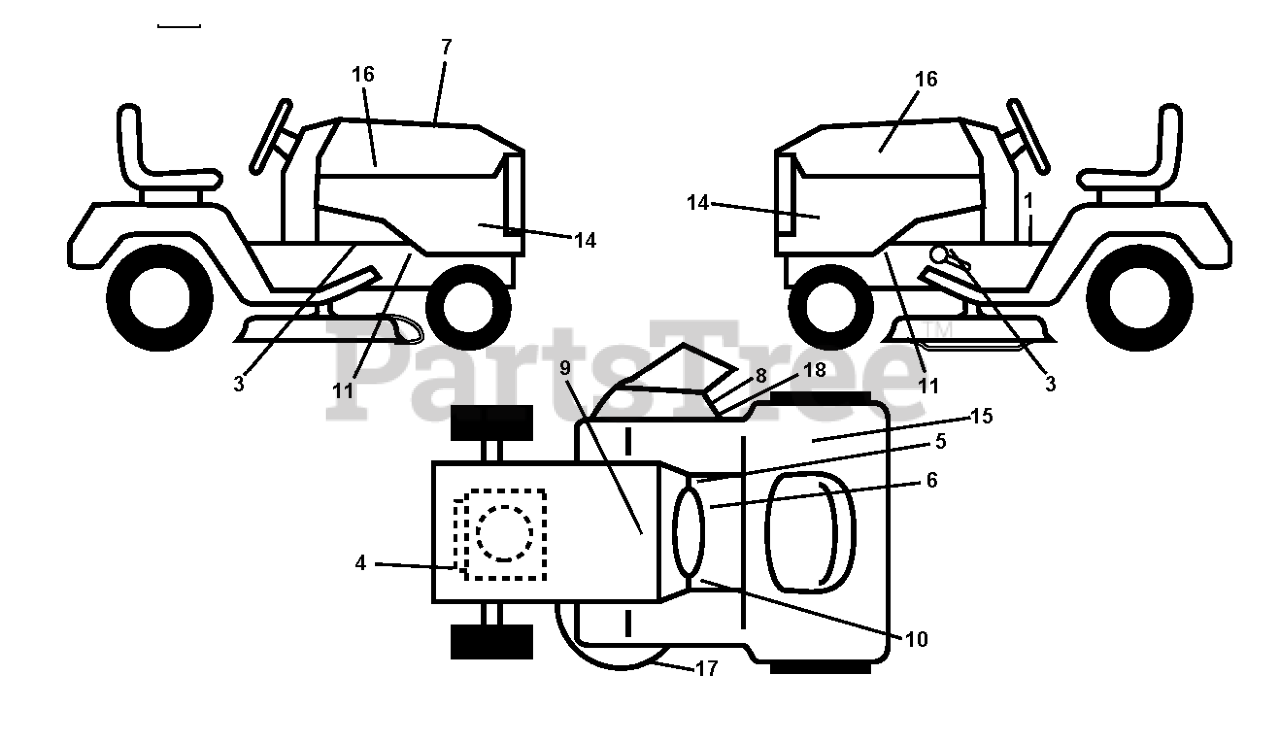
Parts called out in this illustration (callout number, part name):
1	LABEL
4	DECAL
5	DECAL PARK BRAKE
6	DECAL
7	DECAL RPL KO
8	DECAL.INTERNATIONL.CUTFINGER
9	DECAL BTRY SYMBOLS
10	DECAL
14	DECAL PNL SD.
15	DECAL.FENDER
16	DECAL.HOOD.LOGO.ORANGE.HUSQVAR
17	DECAL.MOWER.SCH.48/54
18	DECAL, DEFLECT WARNING
